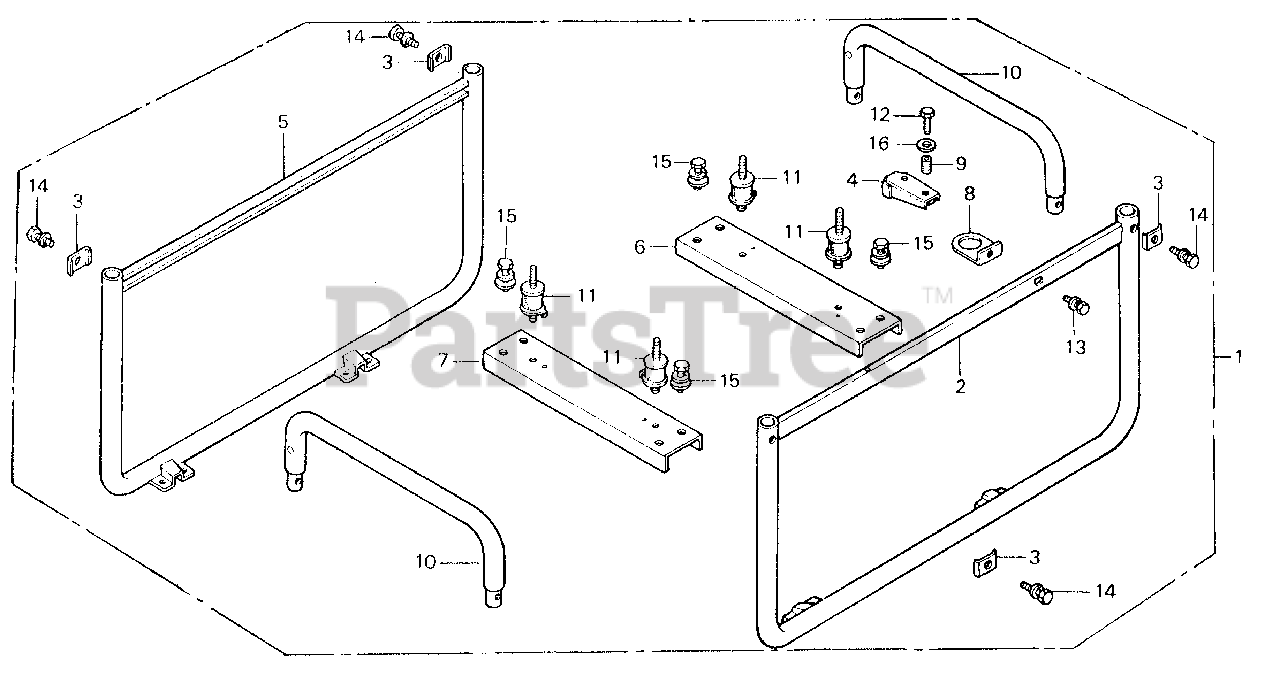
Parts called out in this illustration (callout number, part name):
1	FRAME KIT (NOT AVAILABLE)
2	FRAME, FR. (N/A: SEE ASSEMBLY)
3	PLATE, JOINT
4	STAY, STOPPER RUBBER (N/A: SEE ASSEMBLY)
5	FRAME, RR. (N/A: SEE ASSEMBLY)
6	PLATE, GENERATOR (LOWER) (N/A: SEE ASSEMBLY)
7	PLATE, ENGINE (LOWER) (N/A: SEE ASSEMBLY)
8	STOPPER, ENGINE (N/A: SEE ASSEMBLY)
9	RUBBER, STOPPER (NOT AVAILABLE)
10	HANDLEBAR (NOT AVAILABLE)
11	RUBBER, ENGINE MOUNTING
12	BOLT, HEX. (8X32)
13	BOLT-WASHER (6X12)
14	BOLT-WASHER (8X16)
15	BOLT-WASHER (8X16)
16	WASHER, PLAIN (8MM)
